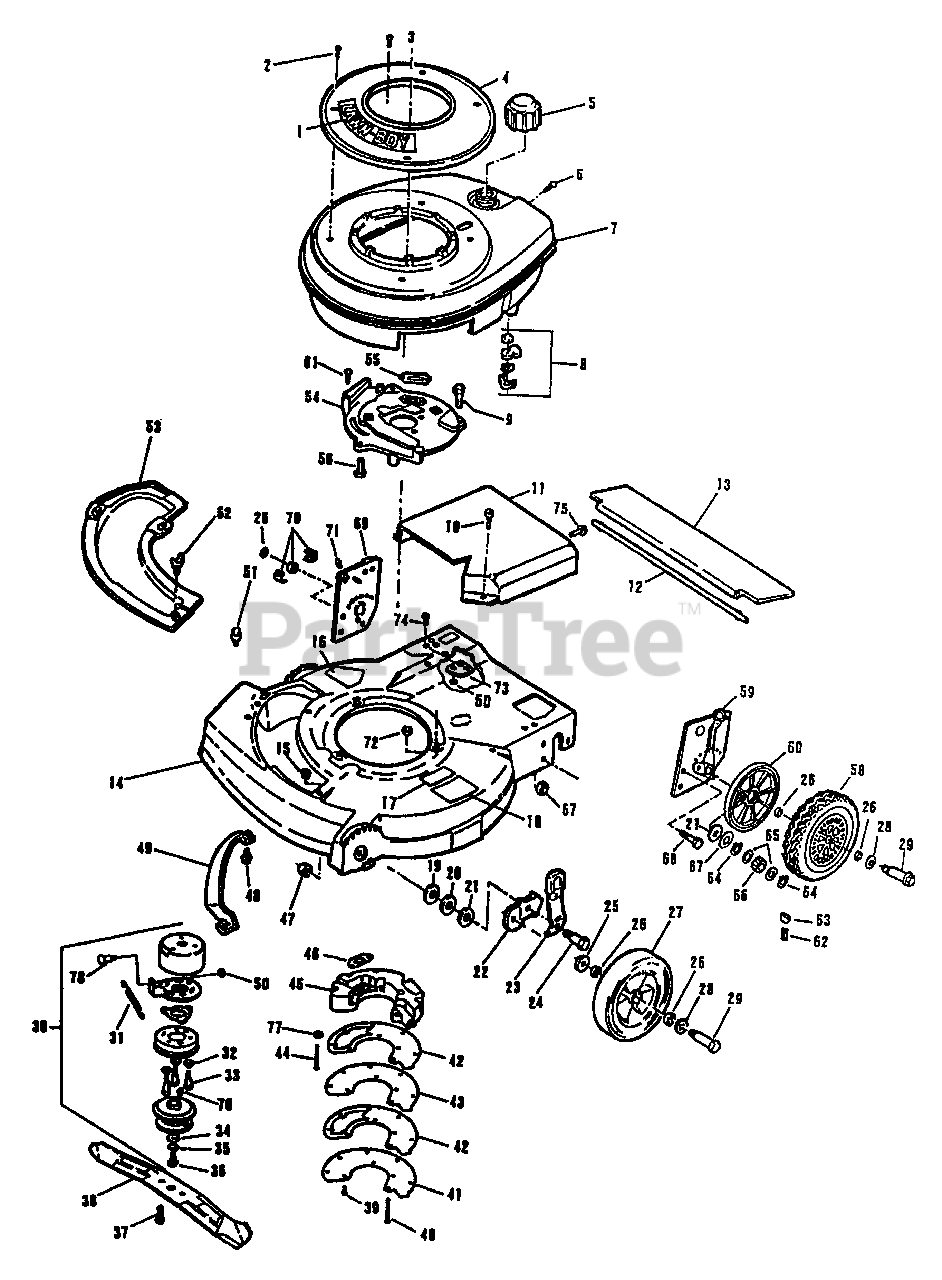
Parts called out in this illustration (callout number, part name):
1	Applique-Starter Base
2	Screw
3	Screw-Starter Mounting
4	Starter Base and Nut Assembly
5	Fuel Cap
6	Screw-Shroud to C.D. Bracket
7	Shroud-Engine
8	Fuel Shut-Off Assembly
9	Screw-Muffler Plate to Housing
10	Screw-Cover Mounting
11	Cover-Drive
12	Rod-Trailing Shield
13	Shield-Trailing
14	Housing
15	Grommet
16	Decal-Blade Contact Warning
17	Decal-Starting Pad
18	Pad-Starting
19	Washer
20	Washer-Shim-Wheel Height Bracket
21	Washer-Shim-Wheel Height Adjust Bracket
22	Bracket-Wheel Height Adjust
23	Knob and Spring Assembly
24	Bolt-Shoulder
25	Washer
26	Washer-Felt
27	Wheel-Front
28	Washer
29	Bolt-Wheel
30	Clutch Brake Assembly
31	Spring
32	Spring Pressure
33	Screw-Shoulder
34	Washer
35	Lockwasher
36	Screw
37	Screw-Sems-Blade
38	Blade-21"
39	Screw
40	Screw
41	Cover
42	Gasket
43	Heat Shield
44	Screw
45	Muffler
46	Gasket
47	Nut
48	Screw
49	Toe Bar
50	Nut-Bolster to Housing
51	Screw-Plate and Chute Mounting
52	Wing Screw
53	Cover Plate
54	Plate-Muffler
55	Gasket-Exhaust
56	Screw
57	Nut
58	Wheel and Tire Asy.-Rear 8"
59	Height Adjuster Assembly-L.H.
60	Cover Wheel
61	Screw
62	Spring
63	Key
64	Retaining Ring
65	Spacer
66	Pinion
67	Washer
68	Screw
69	Height Adjuster Assembly-R.H.
70	Bearing and Retainer Assembly
71	Fitting
72	Nut-Muffler Plate to Housing
73	Bolster-Housing
74	Screw-Bolster to Housing
75	Screw
76	Key
77	Lock Washer
78	Shoulder Bolt
